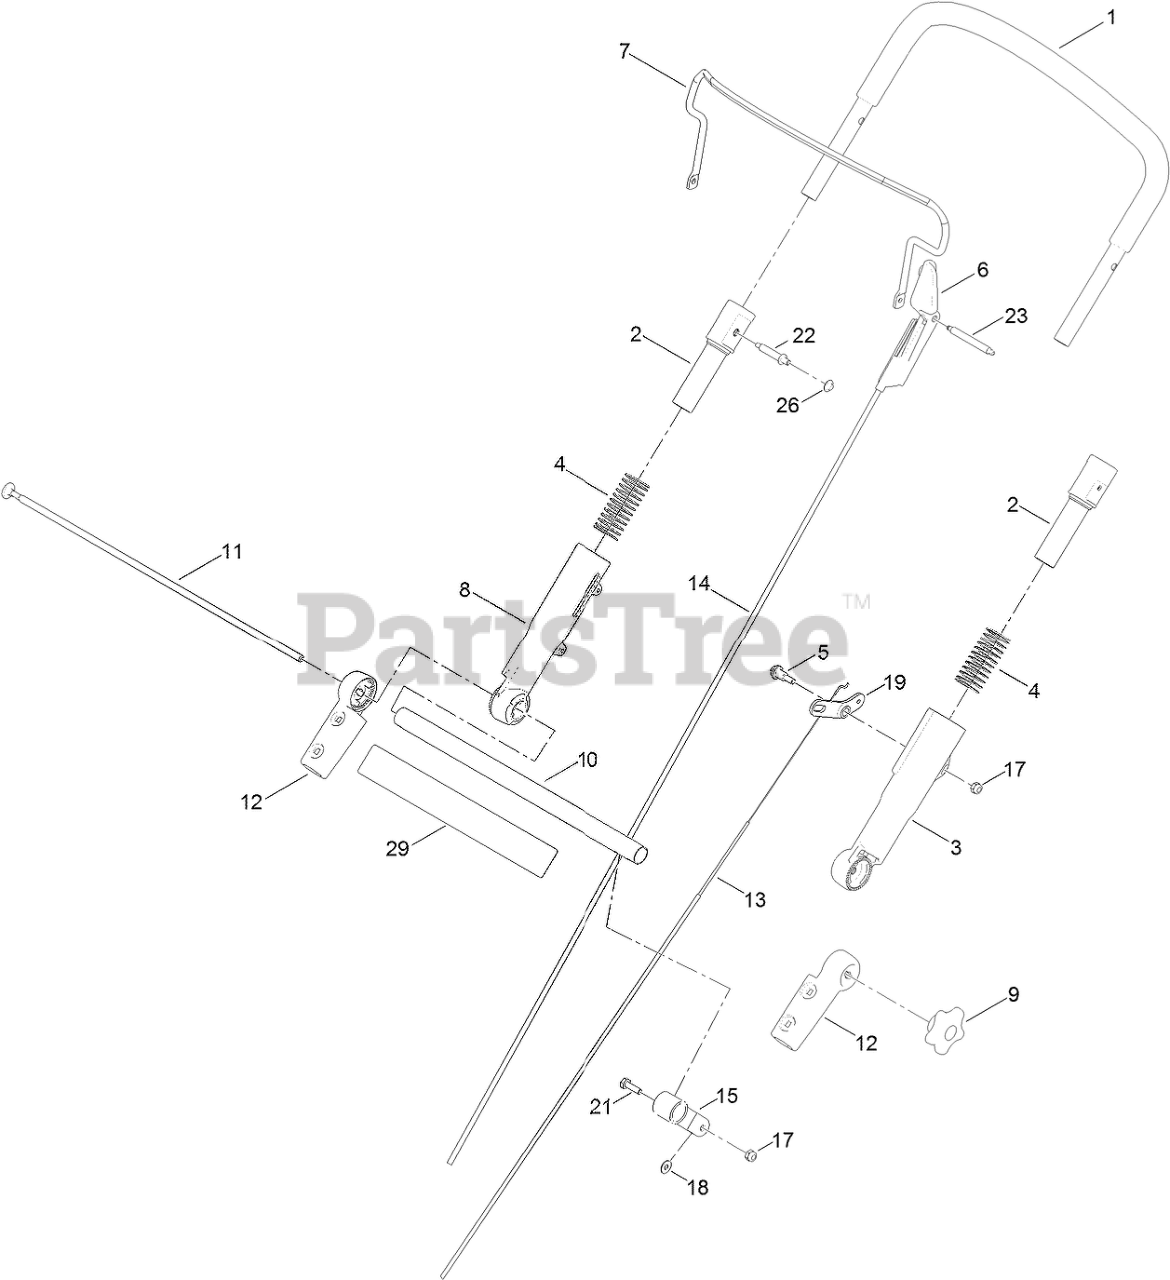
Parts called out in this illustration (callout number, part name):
1	UPPER HANDLE ASM
2	SLEEVE-INNER
3	SLEEVE-OUTER, LH
4	SPRING-COMPRESSION
5	BOLT-SHOULDER
6	STOP-PIVOT
7	BAIL-BRAKE
8	SLEEVE-OUTER, RH
9	KNOB-HANDLE
10	TUBE-CROSS
11	ROD-THREADED
12	MOUNT-HANDLE, LOWER
13	CABLE-TRACTION
14	CABLE-BRAKE
15	CLAMP-CABLE
17	NUT-LOCK, NI
18	WASHER-FLAT
19	LEVER-TRACTION
21	SCREW-HH
22	PIN-HANDLE
23	PIN-BAIL, LH
26	RETAINER-PUSH ON
29	DECAL-ADS
